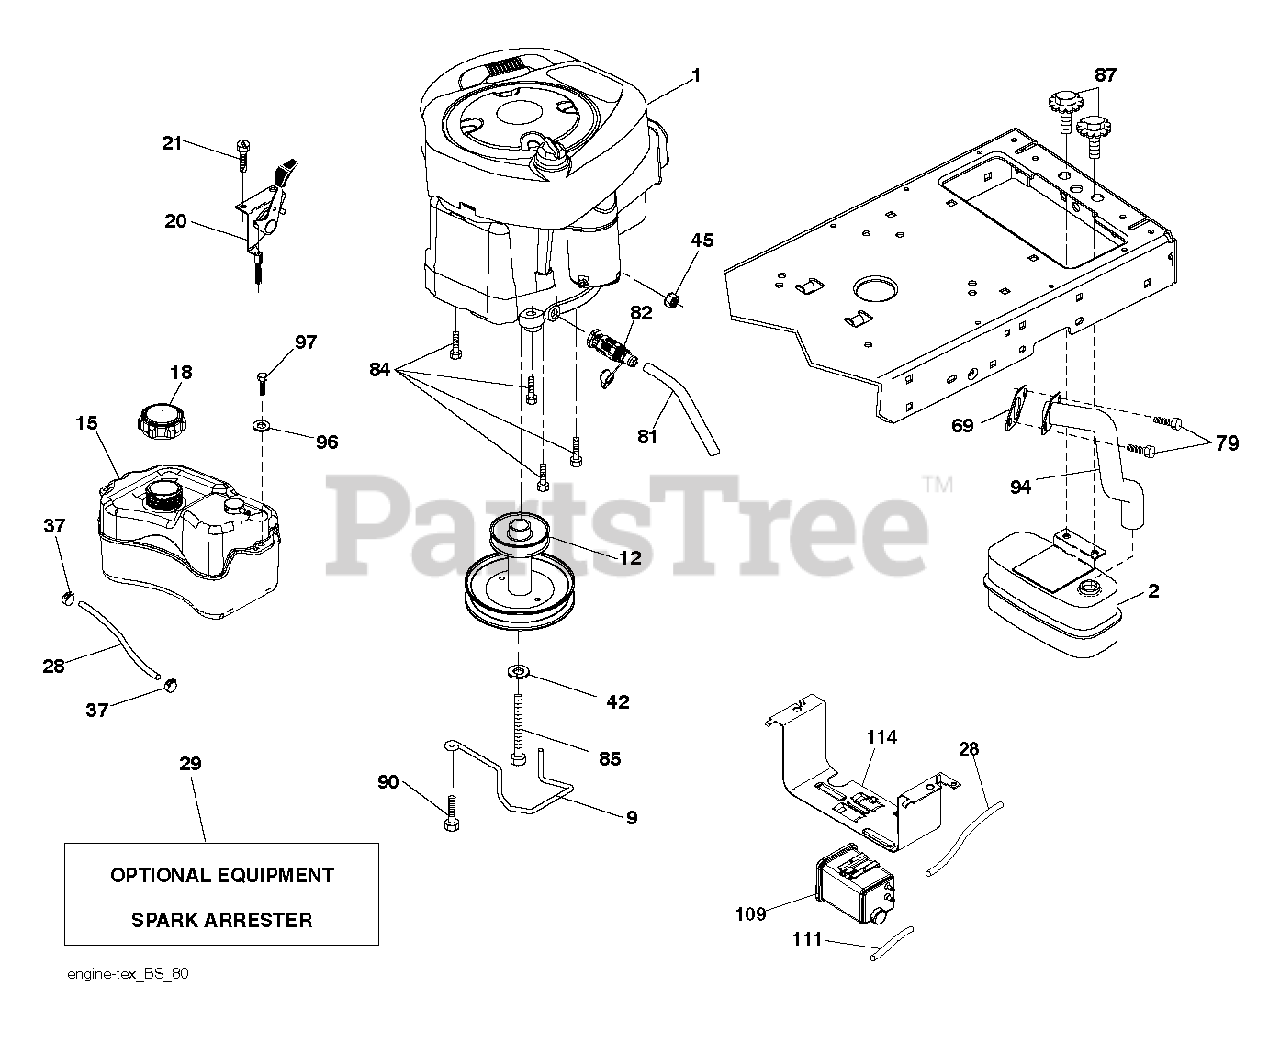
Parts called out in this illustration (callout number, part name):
2	MUFFLER.SINGLE.CYL.KOHL/B&S
9	KEEPER.BELT.ENGINE.4.2
12	PULLY ENGINE
15	TANK ASM.FRONT.CARB.1.5GA.E10
18	CAP ASM.FUEL.2.25"FRT.CARB
21	SCREW.#10 X 0.750.BOS (2 2)
28	LINE.FUEL.20"FRONT.EMI
29	SPARK ARRESTOR KIT
37	HOSE CLAMP
42	LOCKWASHER
45	NUT
79	SCREW.SOCKET HD.5/16-1
81	TUBE, DRAIN OIL ASM.
82	VALUE.OIL.DRAIN
84	SCREW.3/8-16
85	BOLT HEX 7/16-20X4-1/4"
87	BOLT, 5/16-18 X 1 3/4
90	SCREW 3/8-16X1
94	EXHAUST.TUBE.B&S.
96	WASHER
97	SCREW HEXWSHR 1/4-20X3/4
109	CANNISTER, CARBON
111	RP PURGE LINE
